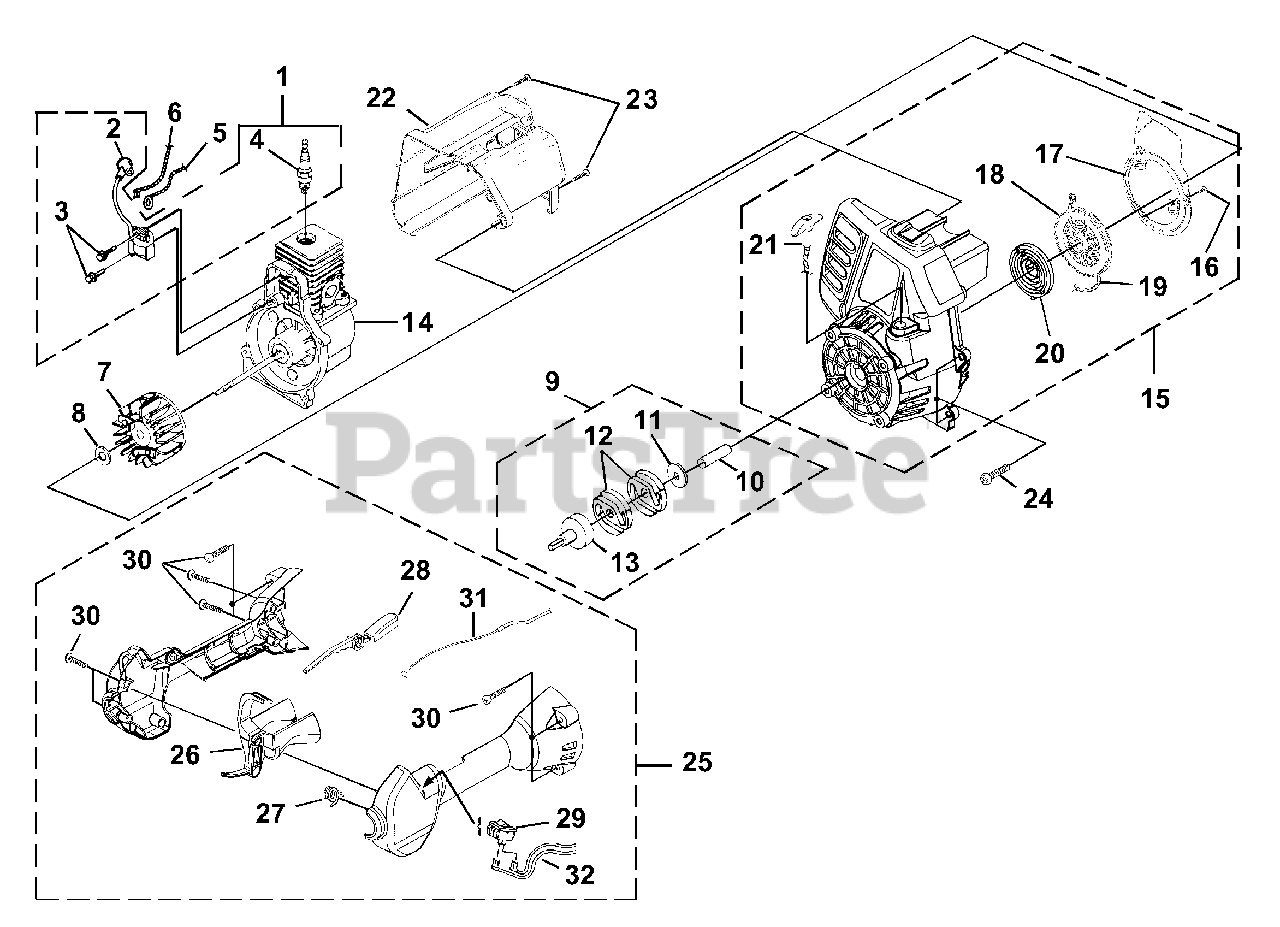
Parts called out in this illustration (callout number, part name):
1	IGNITION KIT
2	TERMINAL & COVER
3	SCREW-Taptite (8-32 X 1")
4	SPARK PLUG
5	LEAD-Electrical
6	LEAD-Electrical
7	ROTOR KIT
8	WASHER-Flat
9	CLUTCH AND DRUM KIT
10	SPACER
11	WASHER-Flat
12	CLUTCH
13	CONNECTOR AND DRUM
14	SHORT BLOCK
15	COMPLETE STARTER ASSEMBLY
16	SCREW-Thread Form (8-16 X 1/2")
17	BAFFLE-Air
18	PULLEY-Starter
19	ROPE-Starter (42")
20	SPRING & CONTAINER
21	GRIP-Starter (Yellow)
22	HOUSING-Rear Kit
23	SCREW-Plastite (10-14 X 3/4")
24	SCREW-Taptite (10-24 X 3/4")
25	CONTROL HANDLE ASSY.
26	TRIGGER-Throttle
27	SPRING
28	THROTTLE INTERLOCK
29	SWITCH
30	SCREW-Taptite (10-14 X 1")
31	CABLE-Throttle
32	LEAD-Electrical
